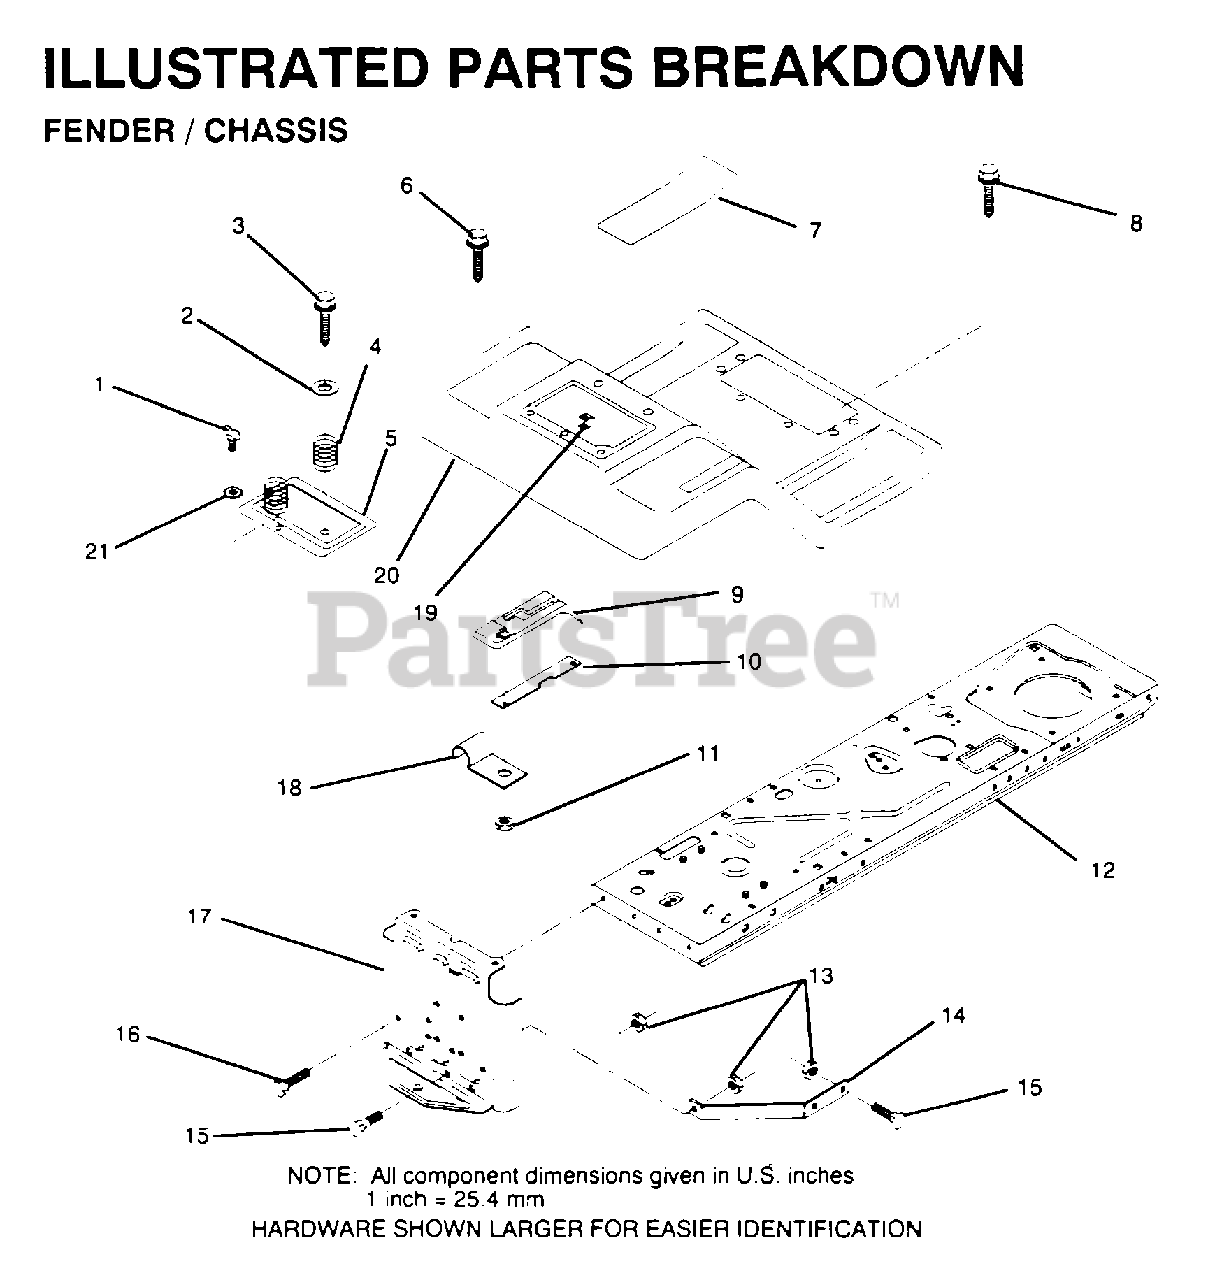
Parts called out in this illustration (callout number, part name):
1	STUD.1/4.TURN
2	WASHER
3	SCREW
4	SPRING COMPRESSIO
6	SCREW LT
8	SCREW
9	CONSOLE SHFT 4SP
11	NUT
12	FRAME ASS'Y
14	"BRACE,DRAWBAR "
15	BOLT
16	BOLT
17	DRAWBAR
18	"CLIP,INSULATOR"
19	RECEPTACLE LT
20	"FENDER,FOOTREST T"
21	RETAINER LT
